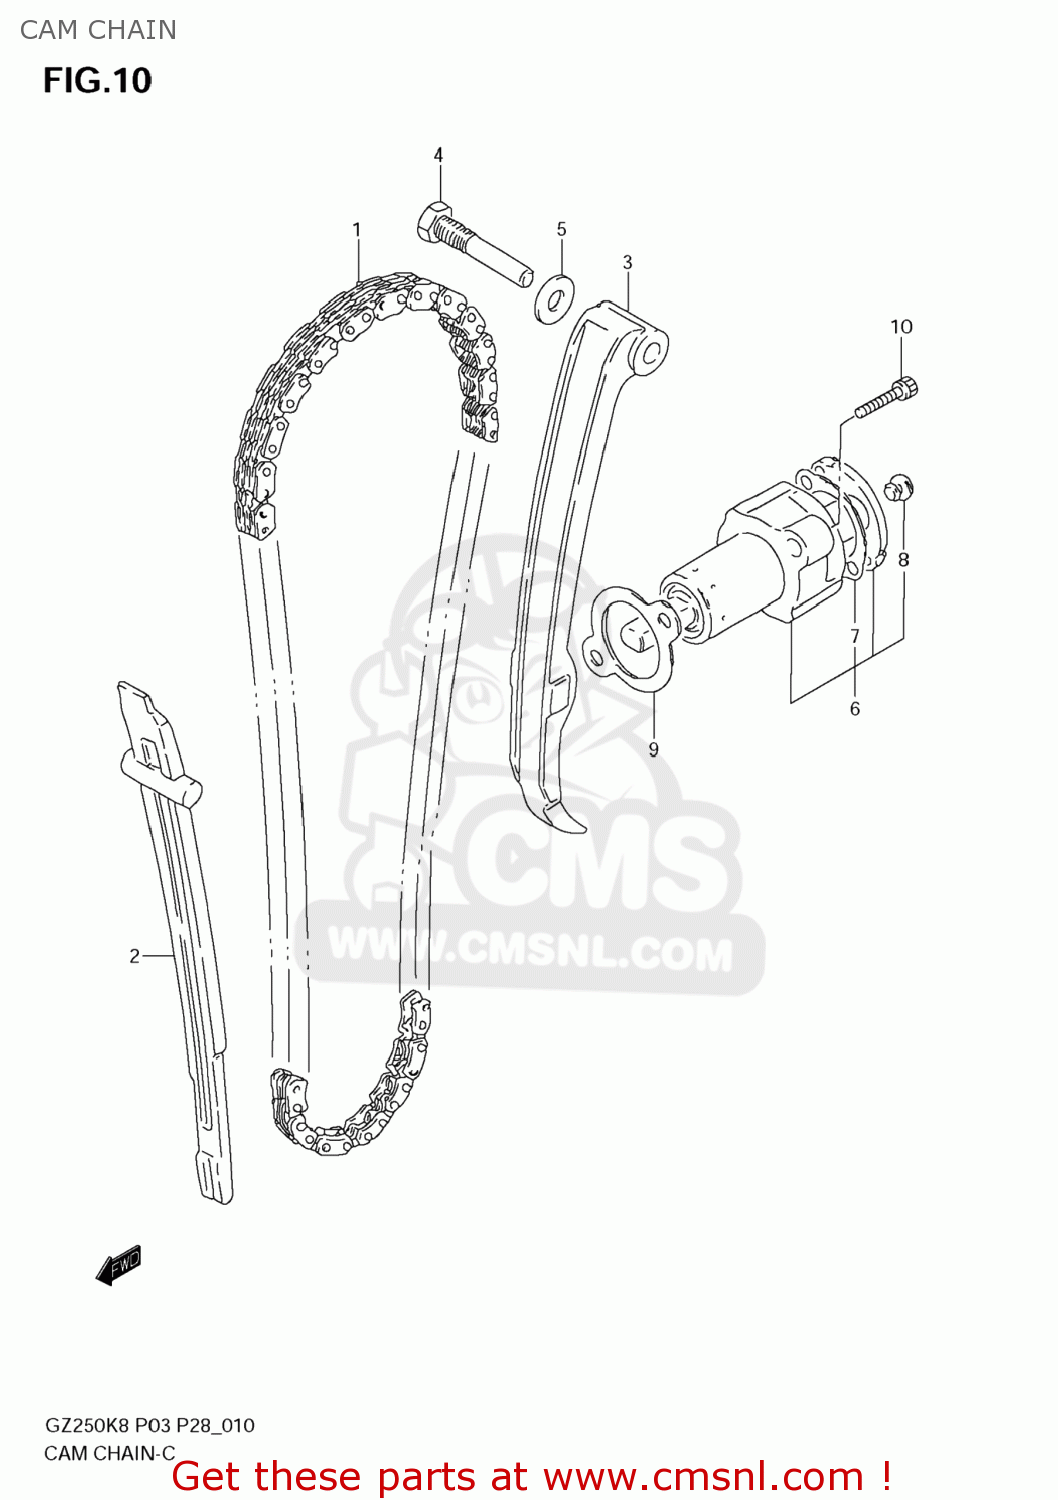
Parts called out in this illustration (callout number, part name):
1	CHAIN,CAMSHAFT DRIVE
2	GUIDE,CAM CHAIN
3	TENSIONER,CAM CHAIN
4	BOLT,CAM CHAIN TENSIONER
5	GASKET(8.2X14X1) (NAS)
6	ADJUSTER ASSY,TENSIONER
7	GASKET,ADJUSTER CAP (NAS)
8	PLUG,ADJUSTER
9	GASKET,TENSIONER ADJUSTER (NAS)
10	BOLT
